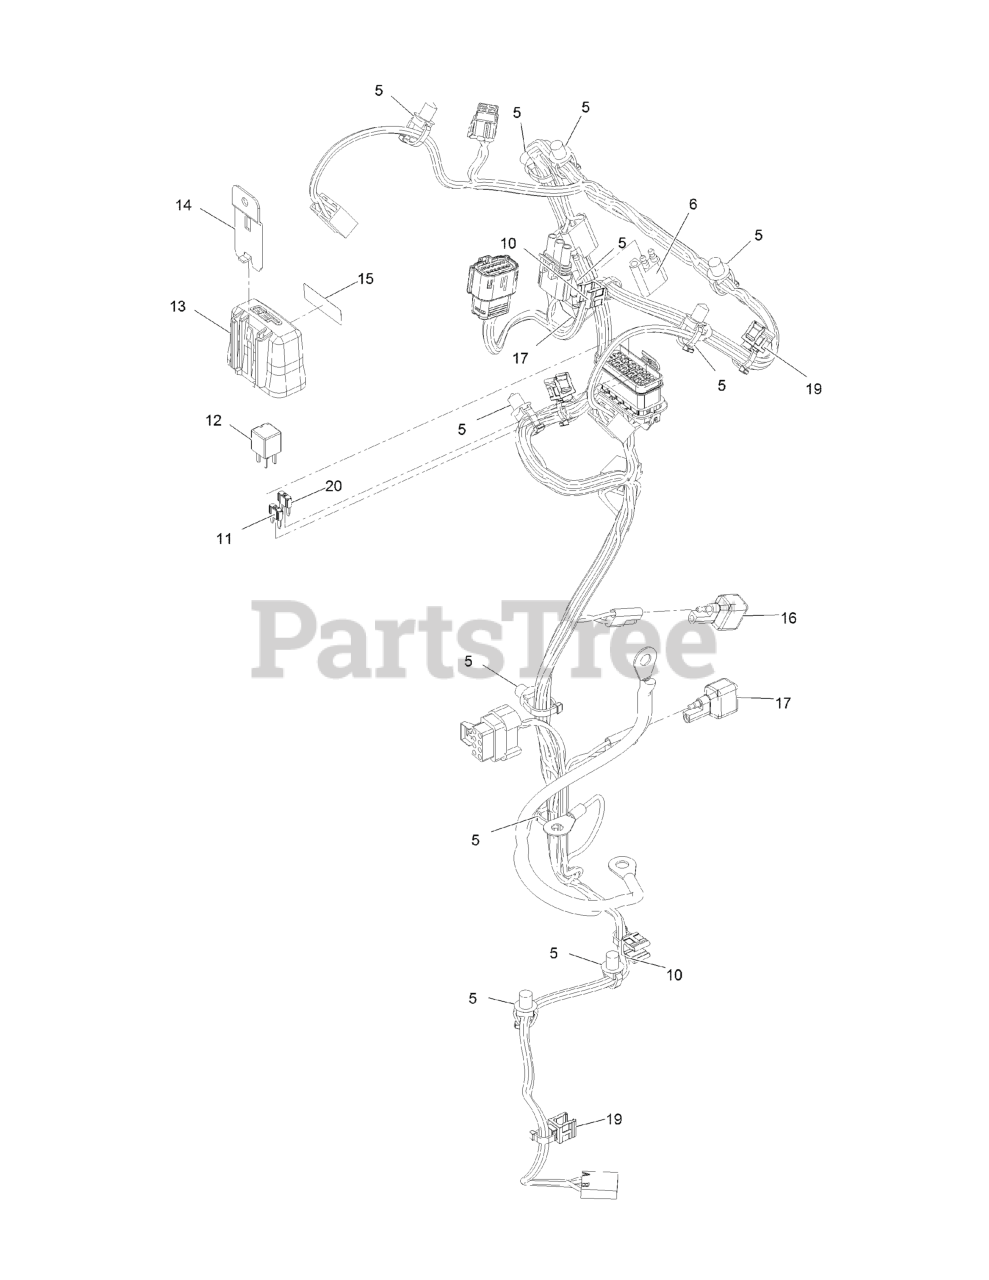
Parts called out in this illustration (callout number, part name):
5	CLIP-TIE
6	Cap-Plug
10	Clip-Edge
11	FUSE-MINI BLADE, 20 AMP
12	RELAY-MICRO
13	COVER-BLOCK, FUSE
14	CLIP-MOUNTING
15	DECAL-FUSE
19	Clip-Edge W/Tie, Perpendicular
20	FUSE-MINI BLADE, 15 AMP
